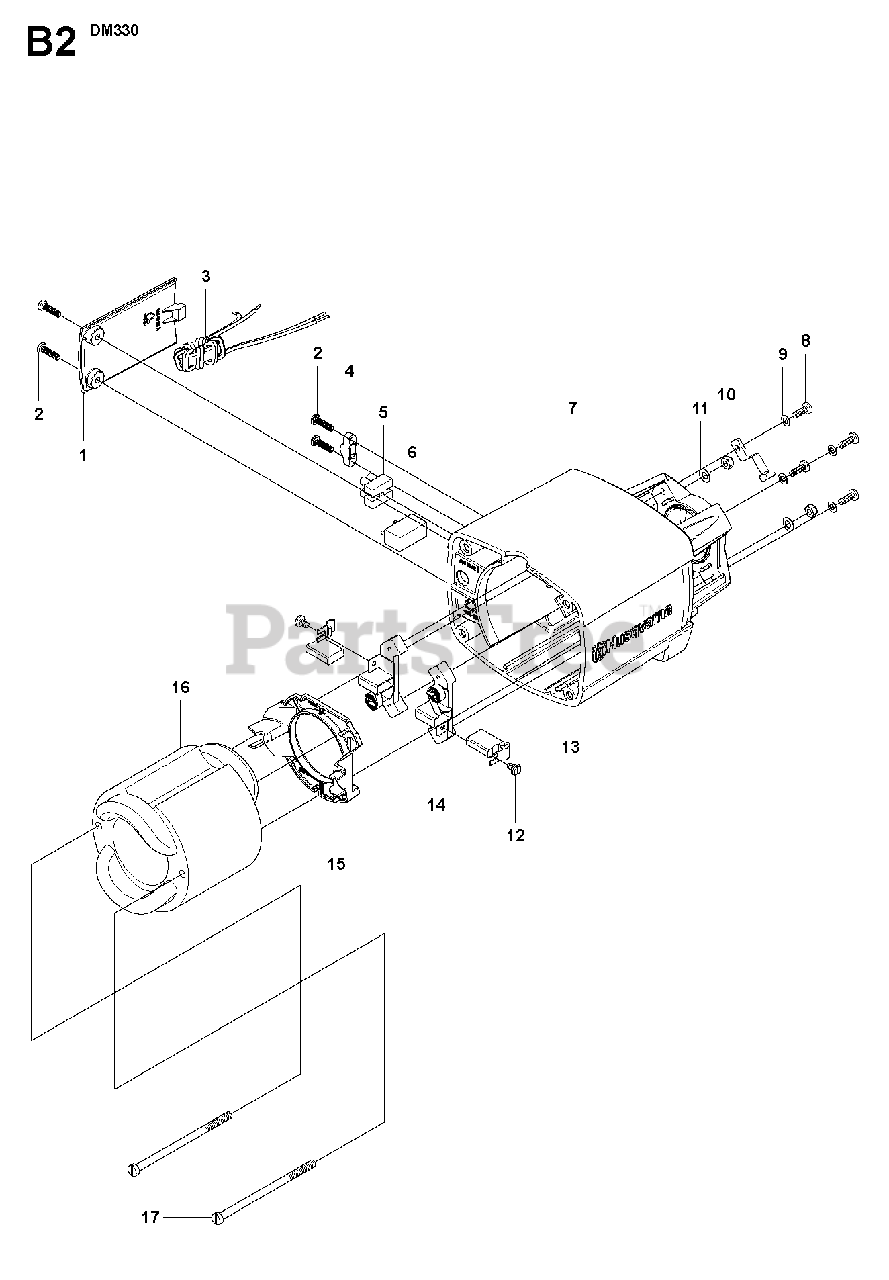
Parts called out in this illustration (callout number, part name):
9	SPRING WASHER
11	SPRING WASHER
12	SCREW SLPANM
13	CARBON BRUSH
16A	STATOR ASSY110V
16B	STATOR ASSY230V
